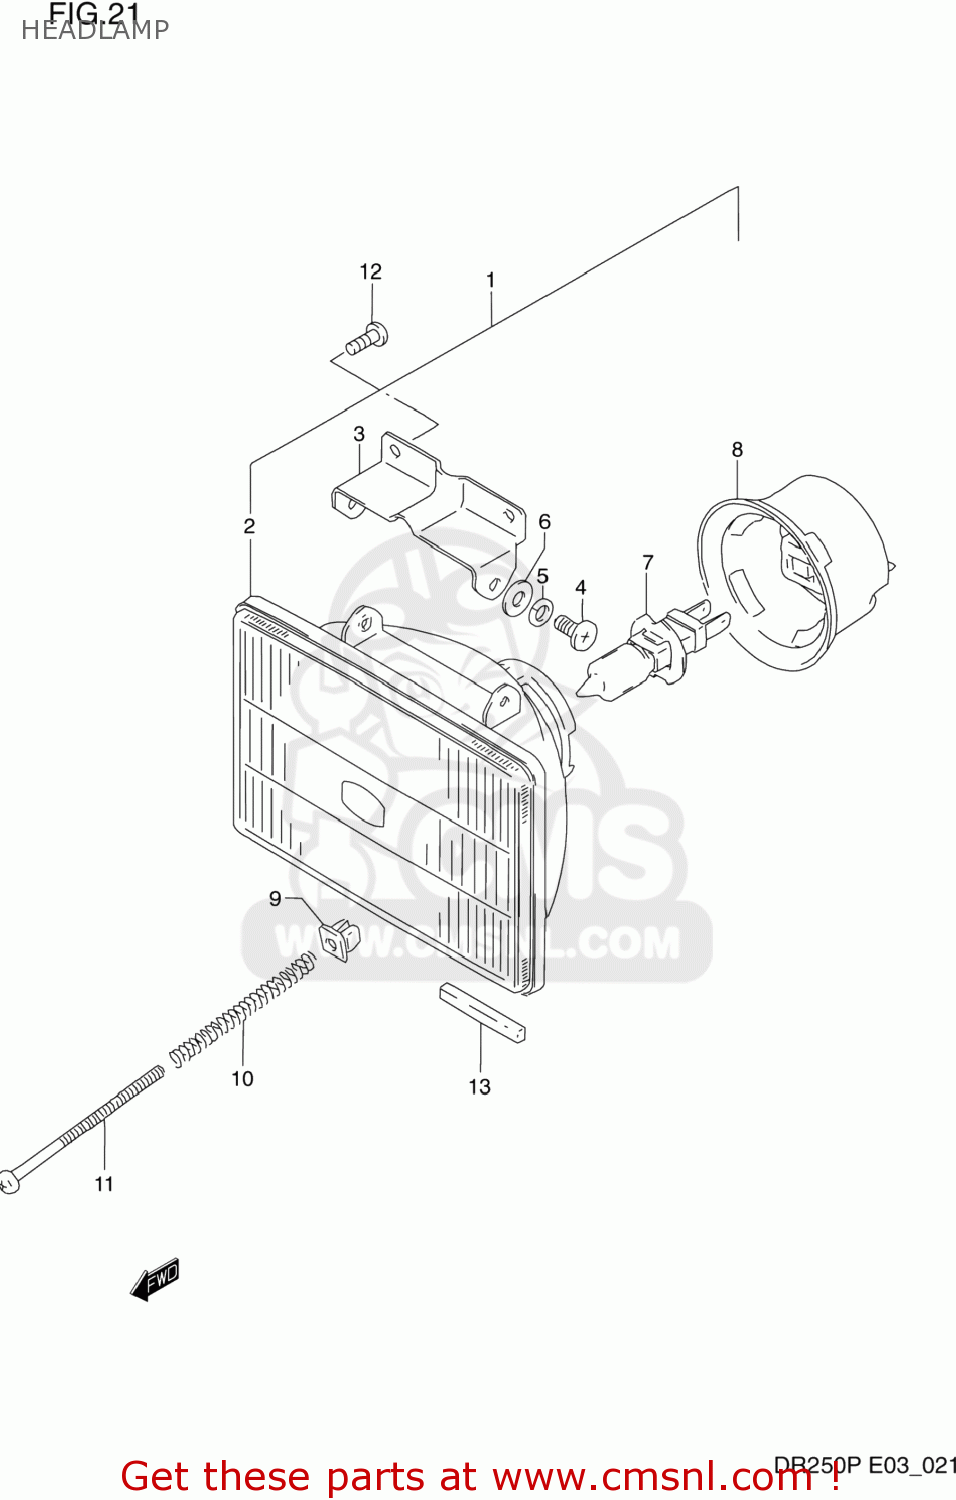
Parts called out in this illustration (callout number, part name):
1	HEADLAMP ASSY
2	UNIT,LAMP
3	BRACKET,LAMP
4	SCREW
5	LOCK WASHER
6	WASHER
7	BULB(12V55W)
8	COVER,SOCKET
9	NUT,HEADLAMP ADJUSTER
10	SPRING,HEAD LAMP ADJUSTER
11	SCREW,HEADLAMP ADJUST
12	SCREW
13	PROTECTOR,BATTERY
